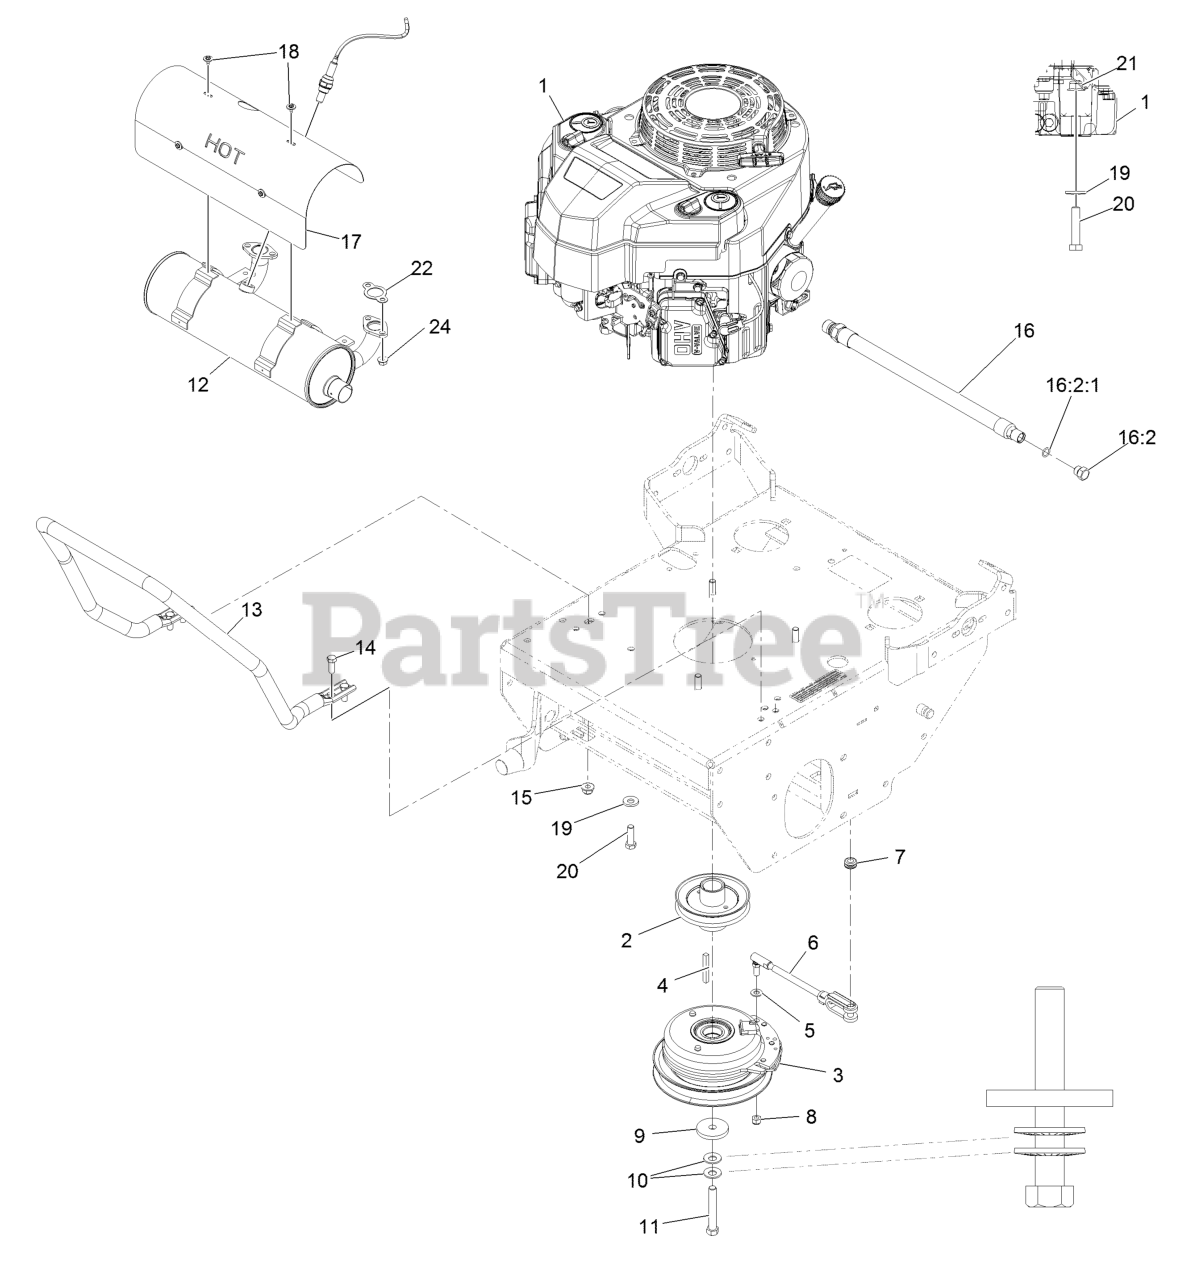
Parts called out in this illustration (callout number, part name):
2	SHEAVE, W/ HUB
3	CLUTCH, 125 FT/LBS, 1.13
4	KEY-SQUARE
5	WASHER-PLAIN
6	ASM, CLUTCH ANCHOR
7	GROMMET
8	NUT-LOCK
9	WASHER-CLUTCH
10	WASHER-SPRING
11	SCREW-HH
12	MUFFLER-TTX, EFI
13	GUARD,AIR CLEANER
14	SCREW-HH
15	NUT-HF, NI
16	OIL DRAIN HOSE ASM
16:2	PLUG-HH
16:2:1	O-RING
17	SHIELD-MUFFLER,TTX EFI
18	SCREW-HH, THREAD FORMING
19	WASHER-SPRING
20	SCREW-HH
21	NUT-HF, NI
22	GASKET-EXHAUST
24	NUT-FLANGE
